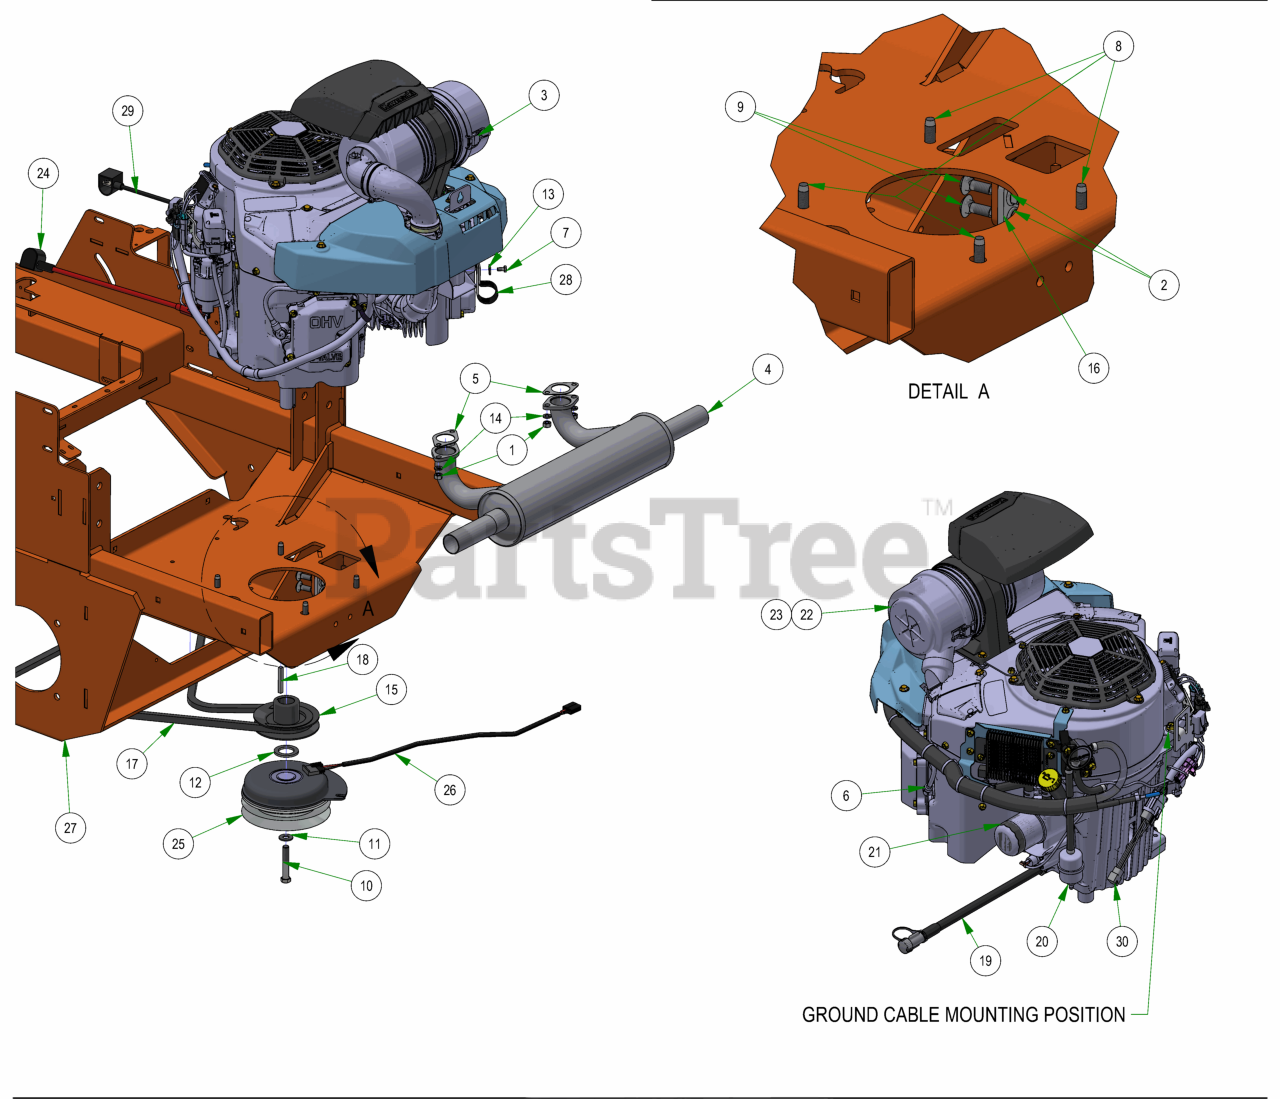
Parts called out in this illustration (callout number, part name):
1	M8-1.25 DIN 934 HEX NUT (CL.8) ZINC
2	3/8-16 NYLON INSERT FLANGE LOCKNUT (GR.F) ZINC
3	Kawasaki FX1000EFI 38.5HP
4	2019 Rebel/Rogue Kawasaki 1000 Muffler
5	Exhaust Gasket
6	Spark Plug - Kawasaki
7	M6-1.0 X 12MM DIN 933 HEX TAP BOLT (CL 8.8) ZINC
8	3/8-16 X 1-1/8HEX WASHER UNSLOT SERRATED (TRI-LOB) TRS ZINC
9	3/8-16 X 1 CARRIAGE BOLT (GR.5) ZINC
10	7/16-20 X 2-1/2 HEX Bolt GR 8 W/ Patch
11	3/8 FLAT WASHER USS (1" OD) ZINC
12	1.140 ID X 1.750 OD X .132 THICK FLAT WASHER PLAIN
13	1/4 USS FLAT WASHER (3/4 OD) ZINC
14	5/16 SPLIT LOCKWASHER ZINC
15	4 3/4 Motor Pulley
16	Rebel Clutch Tab
17	2019 Rebel Pump Belt
18	1/4 X 2 SQ MACHINERY KEY 1018 STL PLAIN
19	Kawasaki Oil Drain
20	Universal Inline Fuel Filter
21	Oil Filter
22	Canister Air Filter- Outer
23	Canister Air Filter- Inner
24	14" Red Battery Cable
26	Clutch Pigtail
27	2023 Rebel Frame - Painted
28	Diesel Hydraulic Hose Clamp
29	Starter Cable
30	Harness Adaptor for Kawasaki EFI
